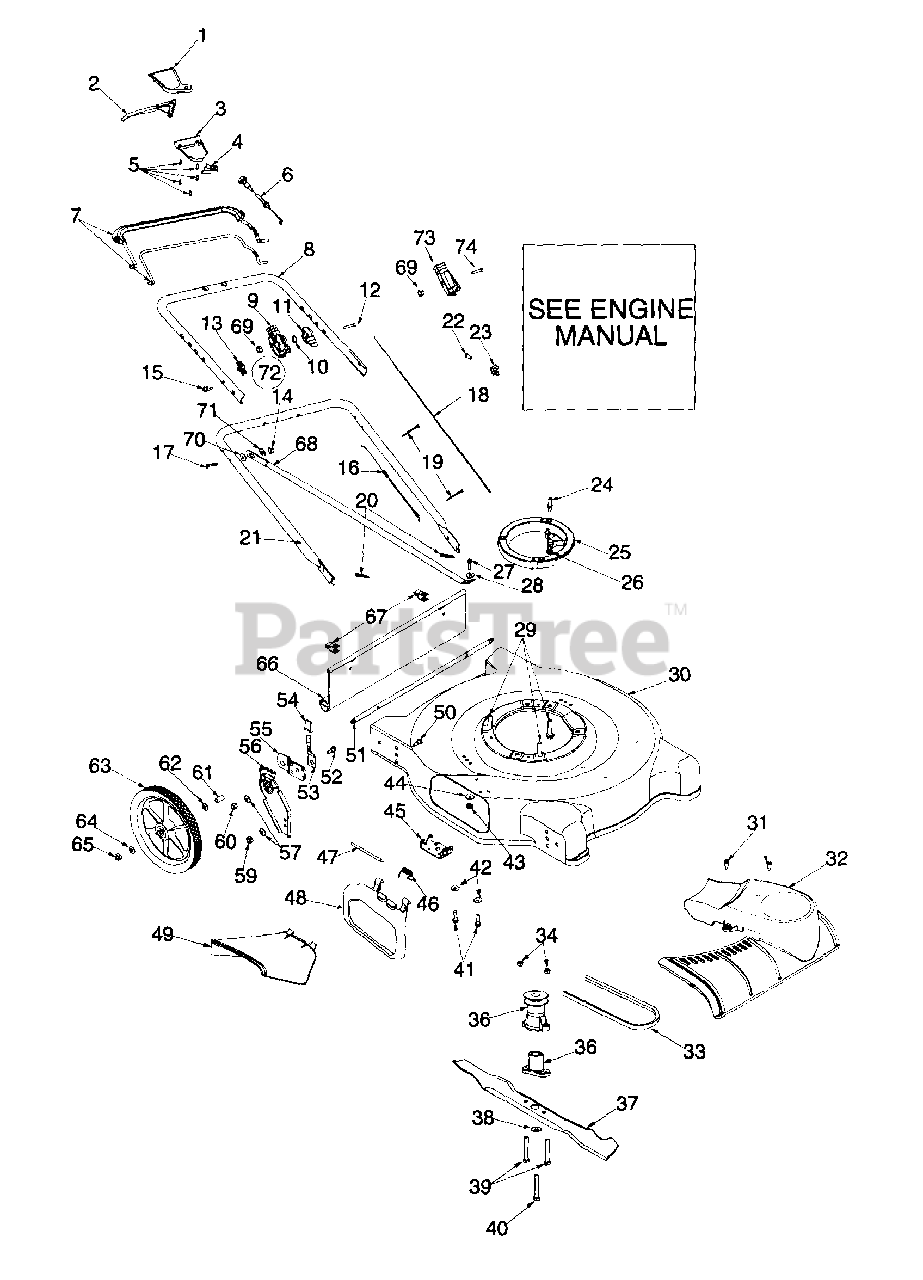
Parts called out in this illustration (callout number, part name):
1	Upper Drive Cover
2	Drive Lever
3	Lower Drive Cover
4	Mounting Cap
5	Screw #10-12 x .75
6	Drive Cable
8	Upper Handle
9	Throttle Housing
10	Curved Washer .663 x .980 x .014
11	Throttle Lever
12	Screw Oval C-Sunk 1/4-20 x 1.81
14	Hex Nut 5/16-18
15	Eye Bolt 1/4-20
16	Throttle Cable: 51" (B&S)
17	Carriage Bolt 5/16-18 x 2.0
18	Control Cable: 39" (B&S)
19	Tie Cable
20	Cotter Pin
22	Hex Screw: T: #10-32 x .625 (B&S)
23	Cable Clamp B&S
24	Pin-Belt Keeper
25	Engine Spacer
26	Hex Nut 1/4-20 Thread
27	Hex Screw 1/4-20 x .620
28	Bell Washer .265 x
29	Tapp Screw w/Hex Lock Wash
30	Deck 22" SD
31	Screw #12 x .457
32	Trans Cover - Black w/Logo
33	V-Belt
34	Hex Lock Nut 1/4-20 Thd.
36	Blade Adapter Kit
37	Blade 22"
38	Bell Washer .396 I.D. x 1.140 O.D. x .095
39	Hex Screw 1/4-20 x 1.50
40	Hex Screw 3/8-24 x 2.50
41	Tapp Screw 1/4-20 x .500
42	Bell Wash .265 x .75 x .062
43	Hex Nut 1/4-20
44	Bell Washer .265 x .75 x .062
46	Torsion Spring
47	Hinge Pin
48	Mulch Plug
49	Chute Deflector
50	Bolt 3/8-24 x .80
51	Rear Axle
52	Shldr Screw .500 Dia x .434
53	Lever Spring
54	Knob
55	Small Pivot Bar - LH
59	Bell Washer .39 x 1.13 x .062
60	Hex Nut 3/8-16
61	Spacer
62	Wave Washer.510 ID x.750 OD
63	Wheel Complete 14 x 1.8 Grey Bar Tread
64	Flat Washer .406 x .812 x .051
65	Top Lock Jam Nut 3/8-16
66	Rear Flap
67	Hinge Clip
70	Saddle Washer .20 ID x .83 OD
71	Lock Washer 5/16
72	Throttle Comp.
73	Throttle Hsg. w/o Lever
74	Scr. 1/4-20 x 1.31 Oval C-Sunk
